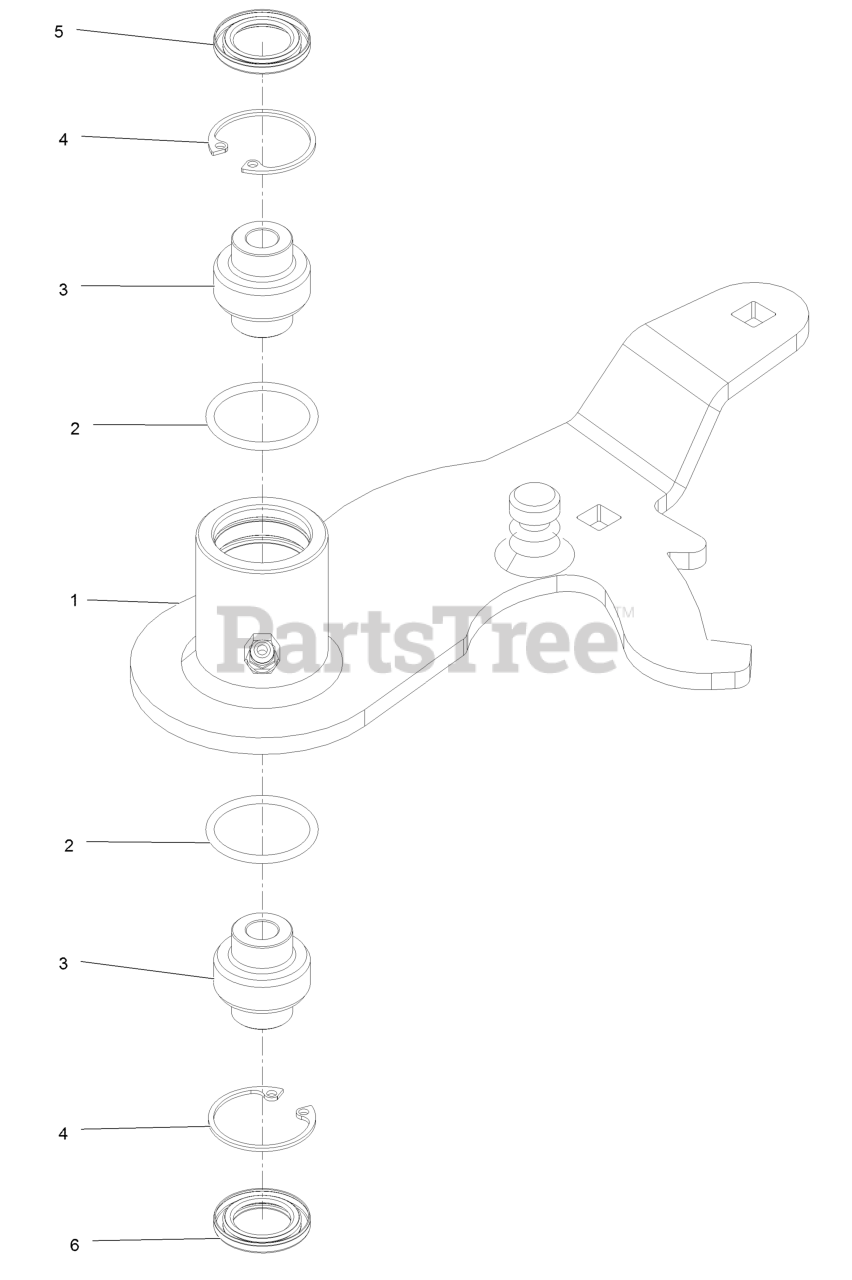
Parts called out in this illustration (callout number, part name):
1	ASM-Idler Arm 96Rd LH [red]
3	Bearing-Spherical
4	Ring-Snap
5	Seal-Lip, Single
6	Seal-Lip, Double
